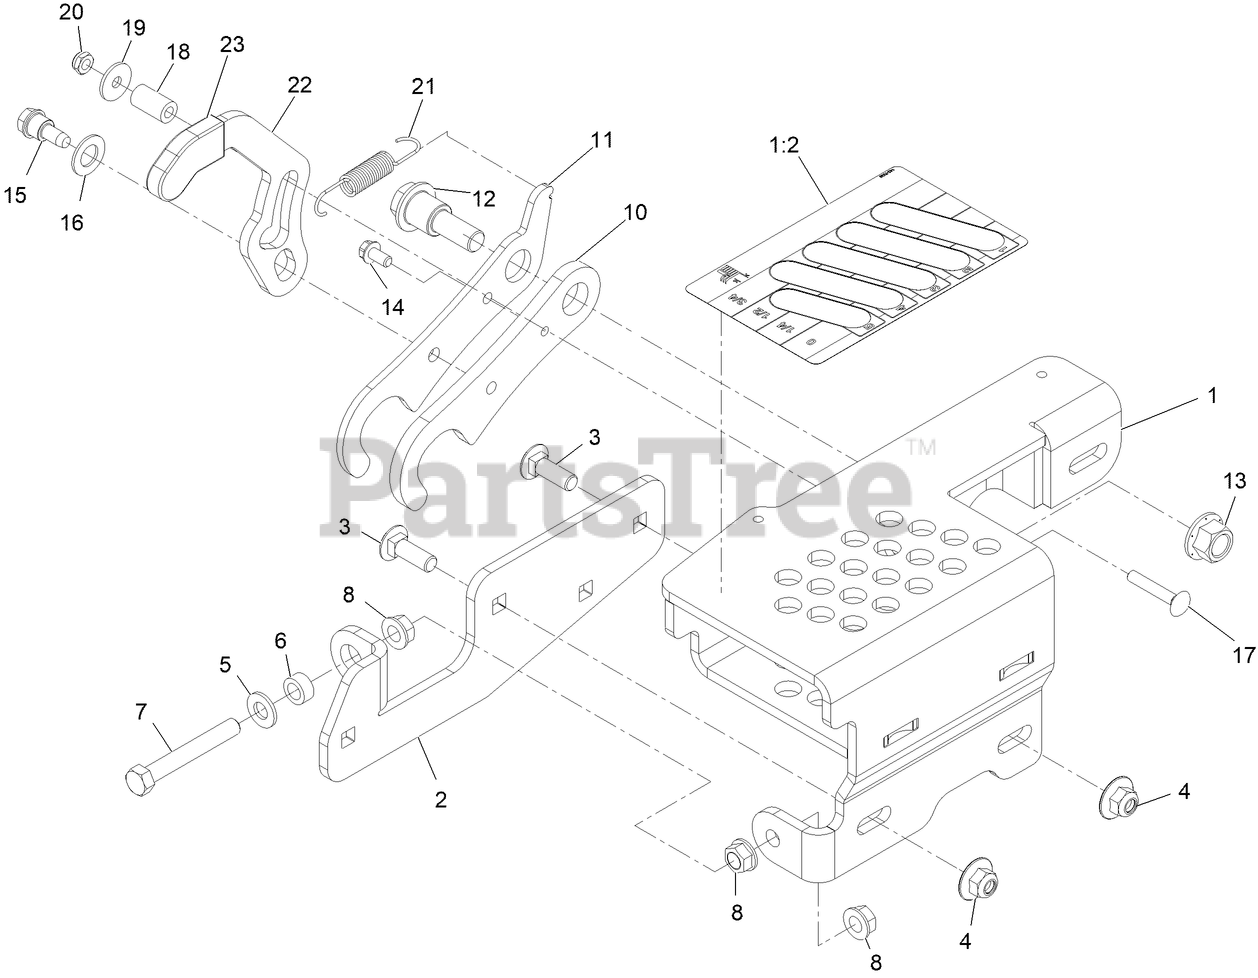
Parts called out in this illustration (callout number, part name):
1	ASM- Box HOC W/Decal
1:2	Decal- Height Of Cut
2	Bracket- Mount HOC
3	Bolt-Carriage 3/8-16 X 1 1/4
4	Nut-Nyloc 3/8-16 Flg
5	WASHER-FLAT
6	Spacer
7	SCREW-TAP
8	NUT-HHF, WHIZ
11	Plate- Pawl
12	Plate- Pawl
13	SCREW-SHOULDER, HHF 1/2-13 X 1.12
14	Nut-Lock 1/2-13
15	SCREW-HWH
16	BOLT-SHOULDER
17	SPACER
18	SCREW-CARR
19	Spacer- 0.50" OD
21	NUT-LOCK, NI
22	Spring- Extension
23	Lever- Transport W/Grip
